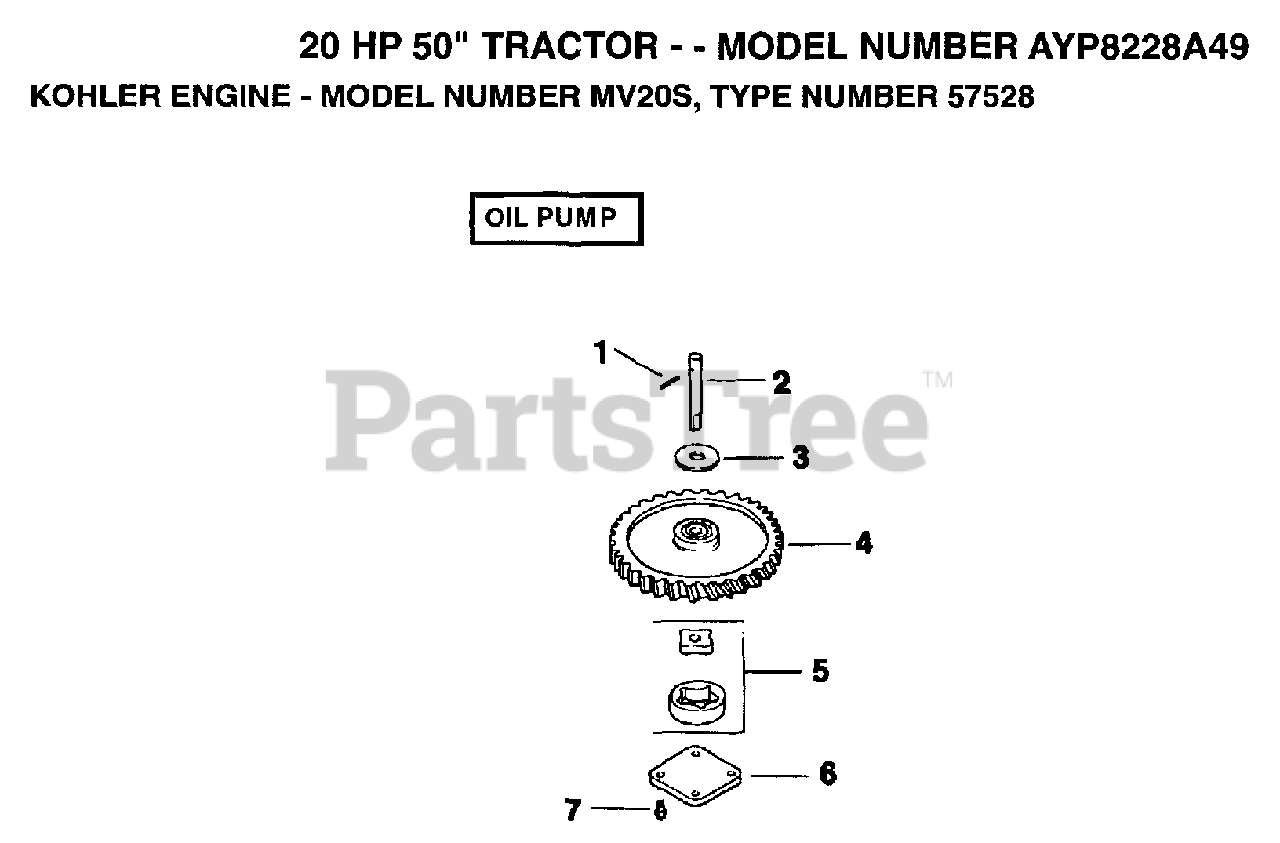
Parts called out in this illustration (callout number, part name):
1	PIN, ROLL
2	SHAFT OIL PUMP
4	GEAR OIL PUMP
6	COVER OIL PUMP
7	SCREW
